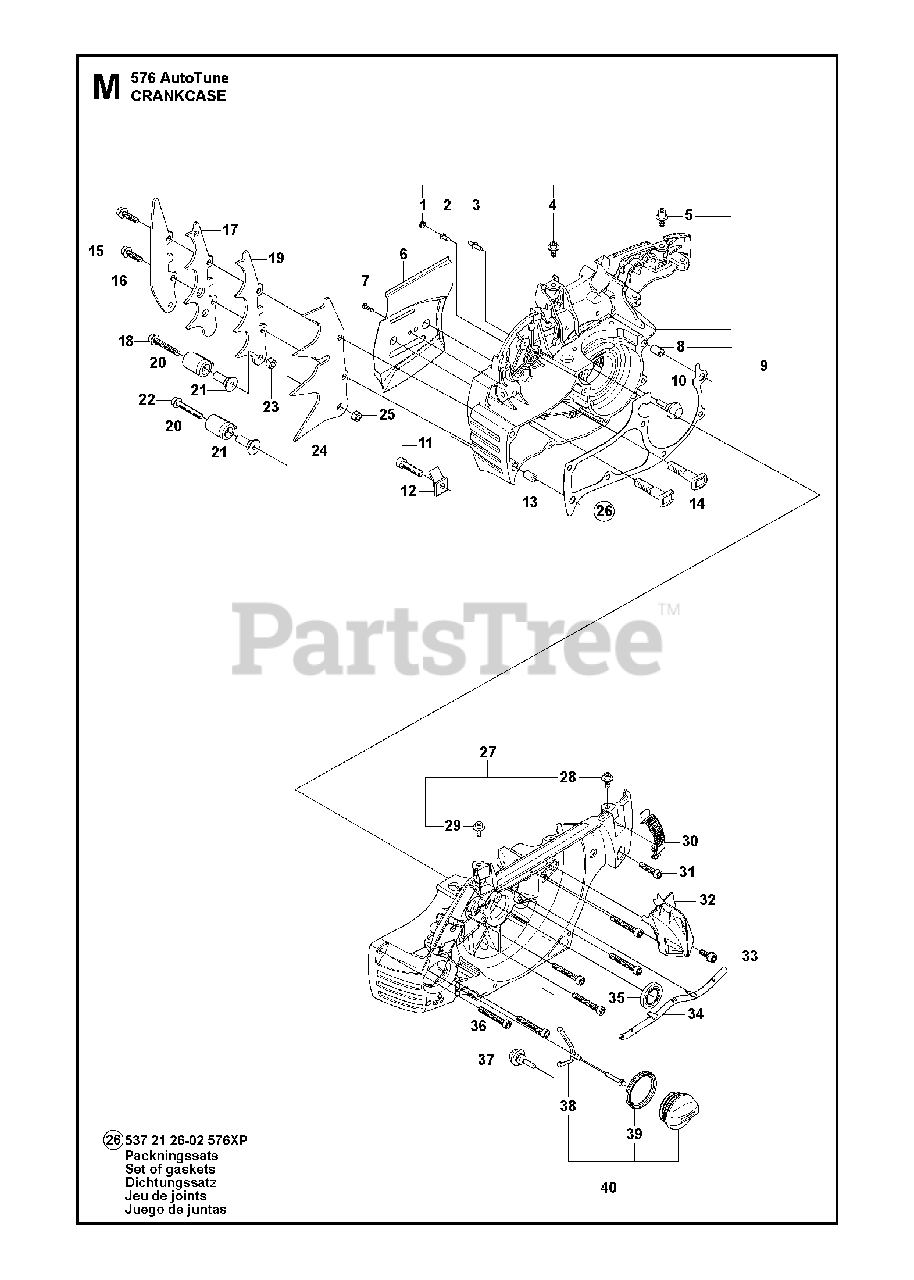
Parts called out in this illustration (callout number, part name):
1	PLUG
2	VALVE-CHECK (DUCKBILL)
3	PIN
4	SCREW IHSCM
5	SCREW IHSCM
8	SLEEVE
9	CRANKCASE ASSY
12	CHAIN CATCHER
13	SLEEVE
14	BOLT
17	FELLING DOG
18	SCREW
19	FELLING DOG
21	CHAIN CATCHER
22	SCREW
24	FELLING DOG
26	GASKET KIT
27	CRANKCASE ASSY
28	SCREW IHSCM
29	SCREW IHSCM
30	BUCKLE ORANGE
30	CLIP GRAY
33	SCREW
35	RADIAL SEAL
38	TANK LOCK
39	SEALING
40	TANK CAP
